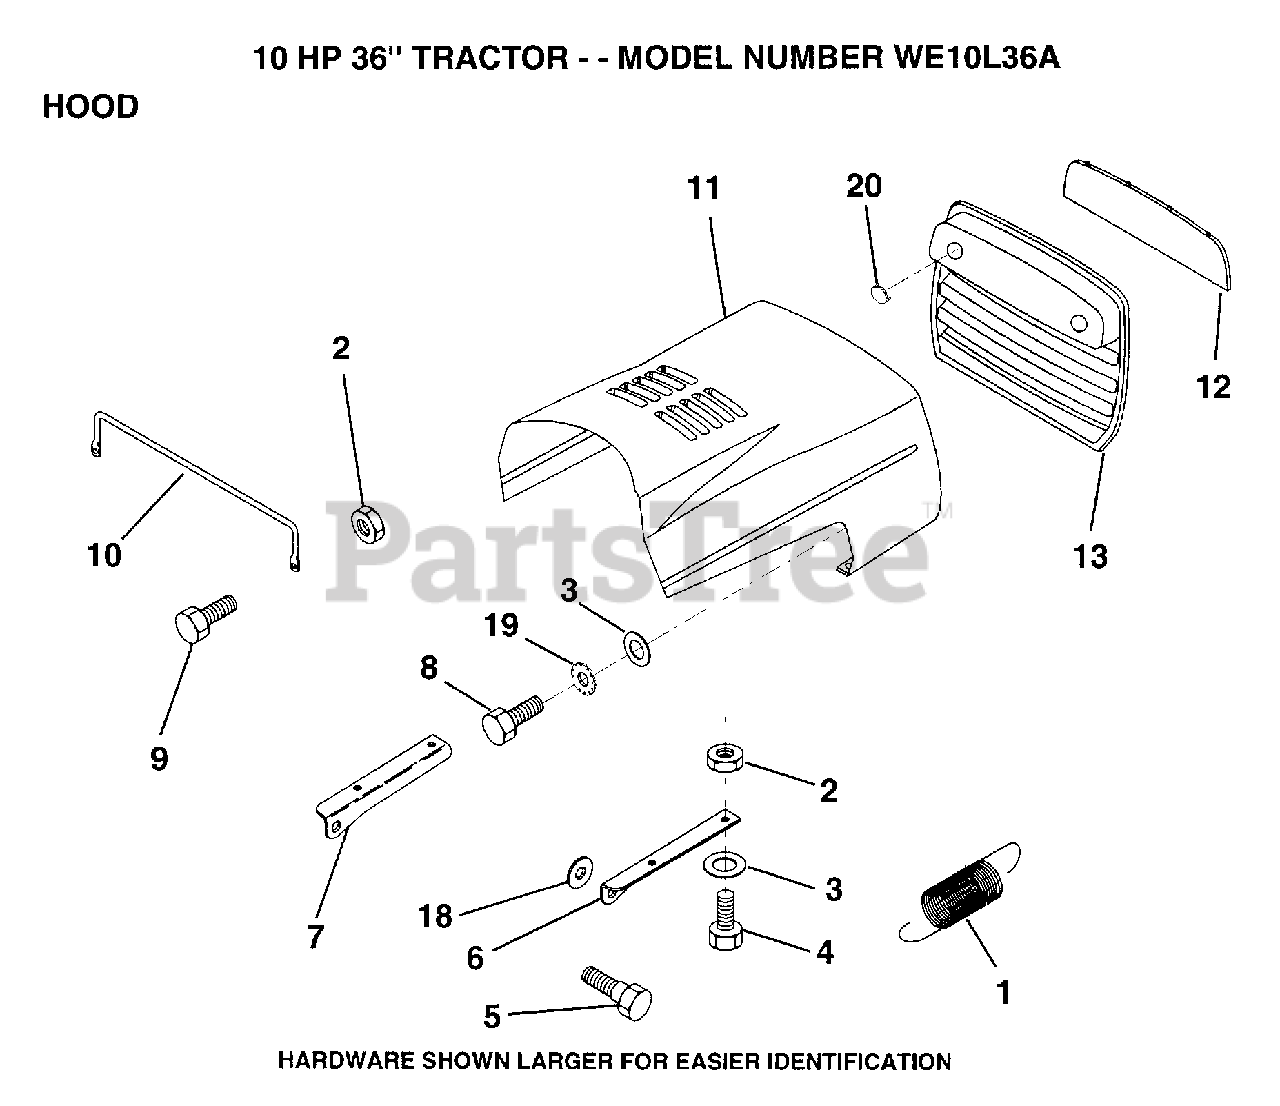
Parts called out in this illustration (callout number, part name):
1	EXT SPRING
2	NUT
3	WASHER
4	BOLT
6	BRKT HOOD RH
7	BRKT HOOD LH
10	"BRACE,HOOD"
11	HOOD
12	LENS
13	GRILL
18	WASHER
19	LOCKWASHER GT
